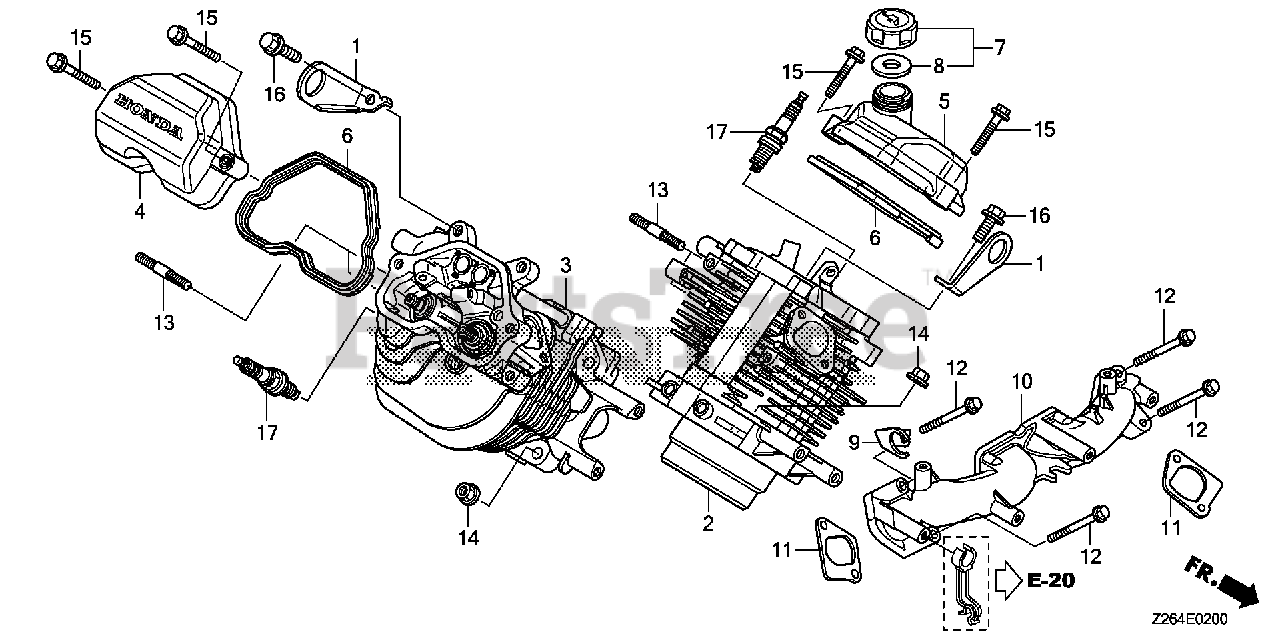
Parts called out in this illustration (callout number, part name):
1	HANGER, ENGINE
2	CYLINDER HEAD (#1)
3	CYLINDER HEAD (#2)
4	COVER, CYLINDER HEAD
5	COVER, CYLINDER HEAD
6	GASKET, HEAD COVER
7	CAP ASSY., OIL FILLER
8	GASKET, OIL FILLER CAP
9	STAY, FUEL TUBE GROMMET
10	MANIFOLD, IN.
11	GASKET, IN. MANIFOLD
12	BOLT, FLANGE (8X55)
13	BOLT, STUD (8X22)
14	NUT, FLANGE (10MM)
15	BOLT, FLANGE (6X30)
16	BOLT, FLANGE (8X16)
17	SPARK PLUG (ZFR5F)
